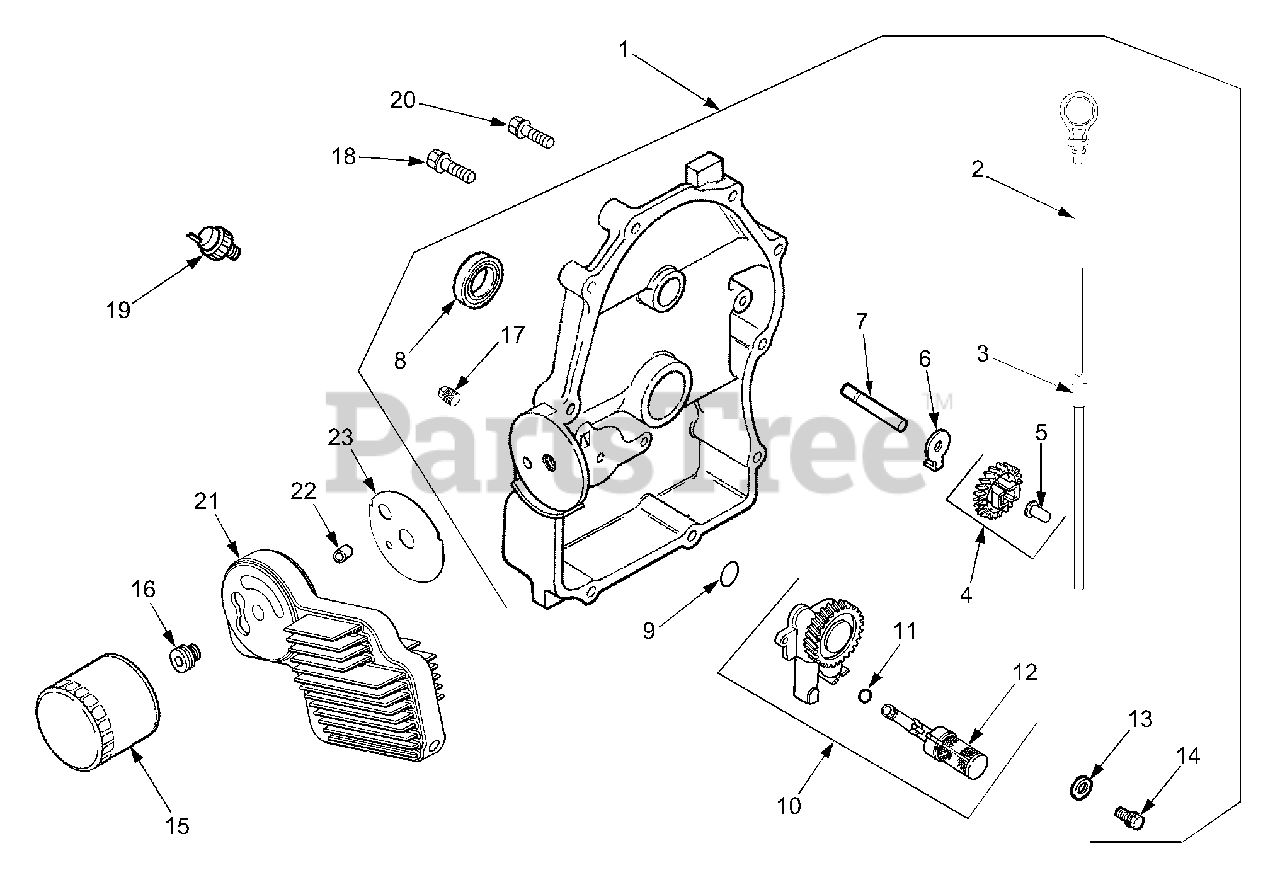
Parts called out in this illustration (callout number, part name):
1	Plate, Closure Assembly
3	Tube, Dipstick
4	Kit, Governor Gear
5	Pin, Governor Regulating
7	Shaft, Governor Gear
8	Seal, Oil (PTO End)
10	Oil Pump Assembly
11	O-Ring, Oil Pick-Up
12	Pick-Up, Oil
13	Washer, Plain
14	Screw, Hex Flange M6 x 1 x 25
15	Filter, Oil
16	Nipple, Oil Filter
17	Plug, Pipe 1/8"
18	Screw, Hex Flange M8 x 1.25 x 45
19	Switch, Pressure
20	Screw, Hex Flange M8 x 1.25 x 45
22	Pin, Locating
23	Gasket, Adapter
